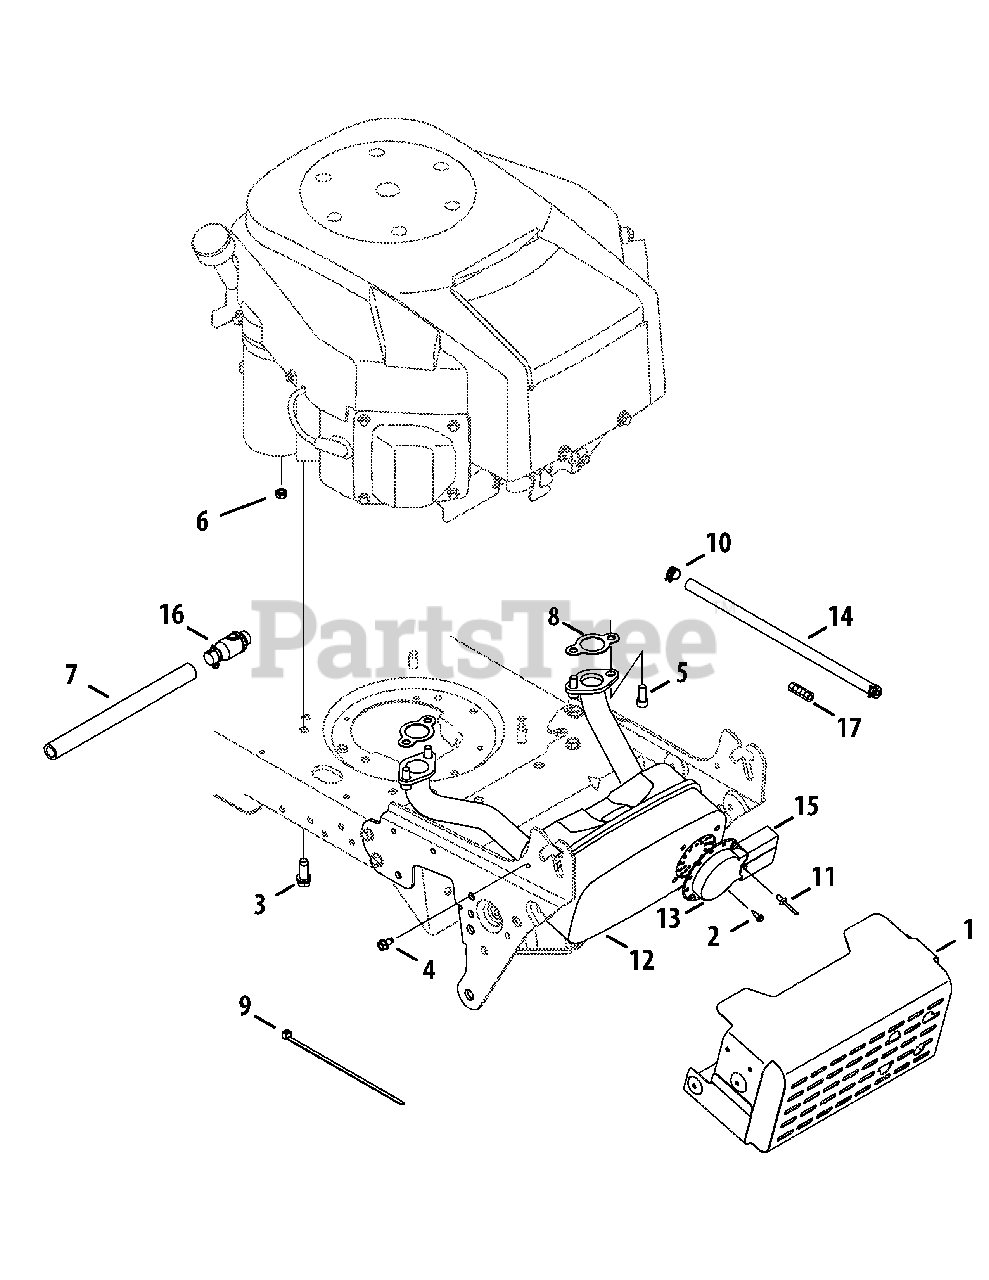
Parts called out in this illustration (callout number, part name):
1	Shield Ass’y, Muffler
2	Screw, Ab, #8-18, 0.500,
3	Screw, Self-tapping, 3/8-16, 1.000,
4	Screw, Self-tapping, 1/4-20, 0.500,
5	Screw, Socket Head, 5/16-18, .750
6	Nut, Sems, 1/4-20
7	Hose, Extension, Oil Drain
8	Gasket, Exhaust
9	Cable, Tie, 3/16 x .05 x 7.4
10	Clamp, Hose, .490 Dia.
11	Rivet, Pop, .188 Dia x .300
12	Muffler, Intek Twin
13	Deflector, Muffler
14	Hose, Fuel, Low Permeation, 1/4
15	Deflector, Muffler, Long
